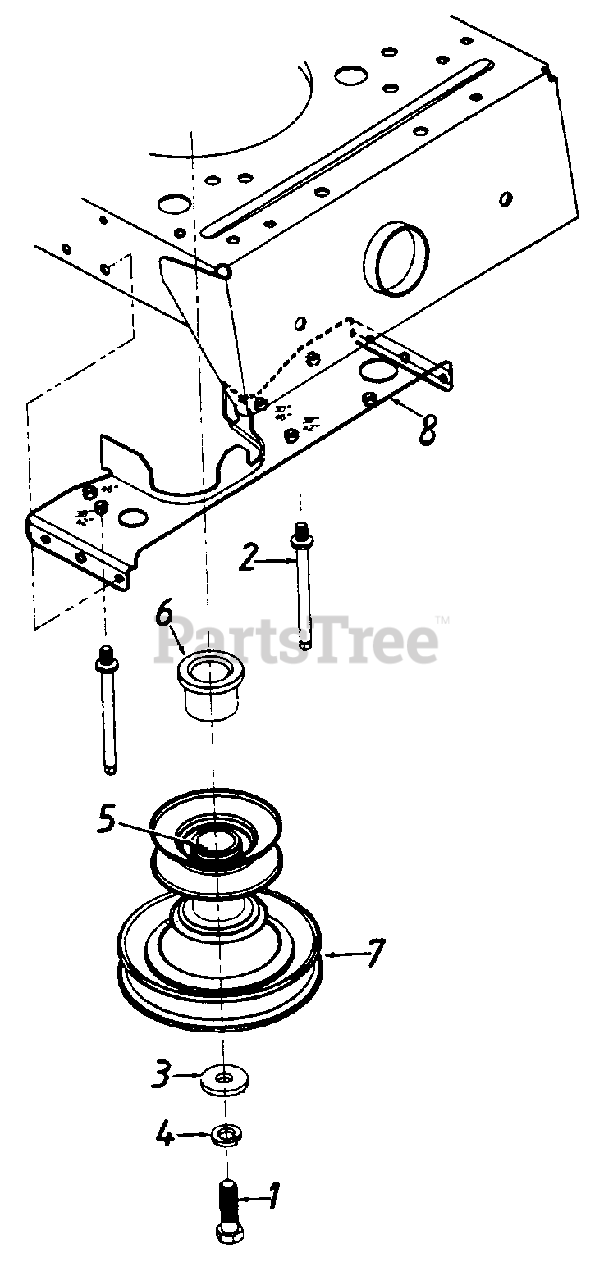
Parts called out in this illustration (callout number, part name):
1	Hex Bolt 7/16-20 x 1.5" Lg.
2	Belt Guard Stud 3.6" Lg.
3	Fl-Wash. 7/16" I.D. 1.25" O.D.
4	L-Wash. 7/16" I.D.
5	Sq.-Key 1/4" x 2" Lg.
6	Spacer
7	Engine Pulley
